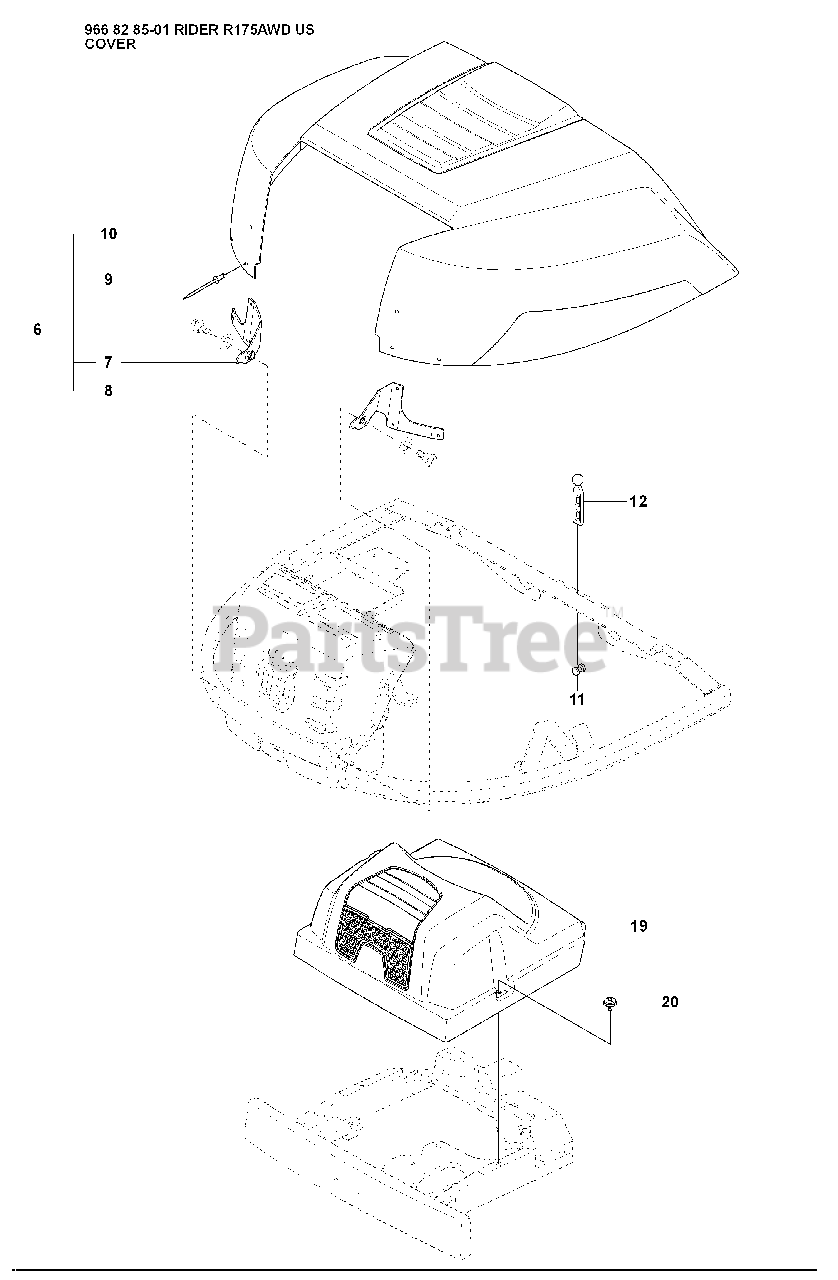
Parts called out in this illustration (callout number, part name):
6	ENGINE HOOD ASSY
7	HINGE
8	HINGE
10	ENGINE HOOD ASSY
12	SUPPORT STRAP
19	COVER
